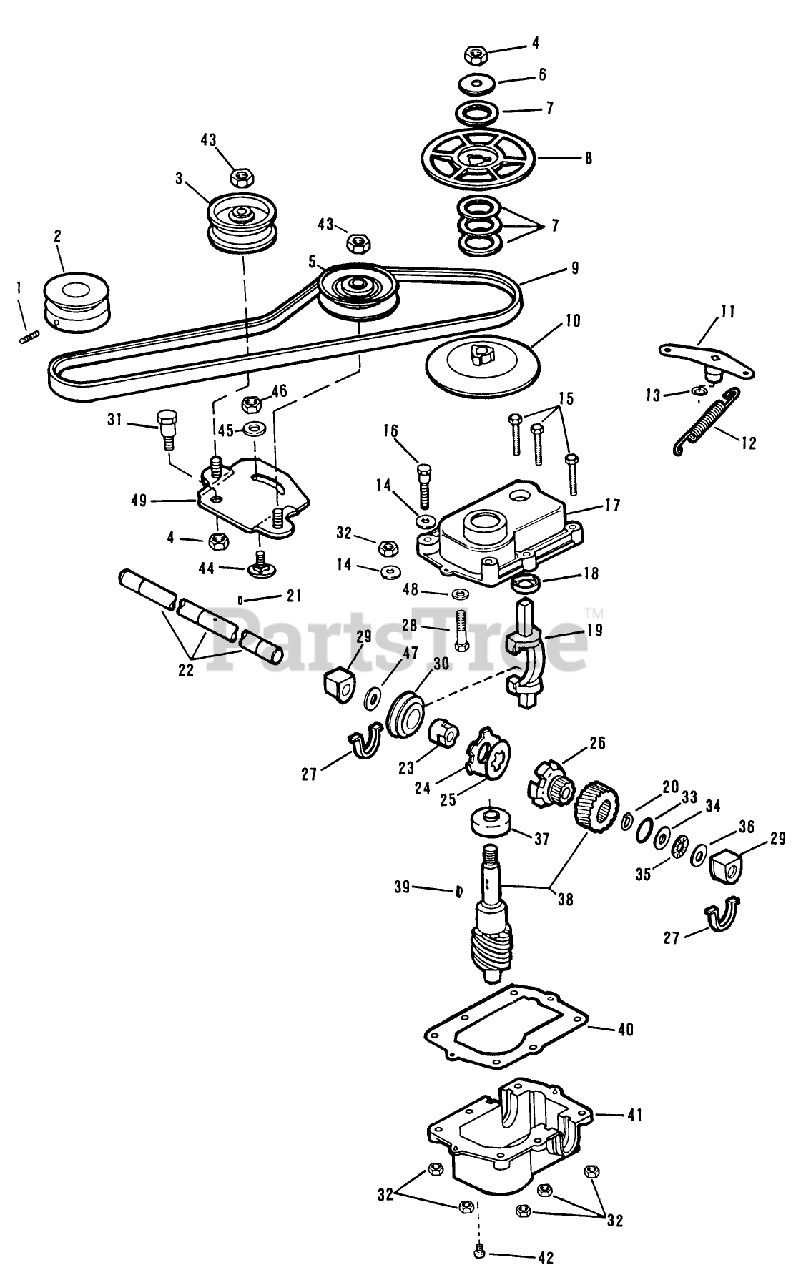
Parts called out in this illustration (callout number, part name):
1	SET SCREW F
2	PULLEY ENG F
3	PULLEY NEWHAM IND *B
4	LOCKNUT
5	IDLER NEW HAM IND
6	WASHER
8	PULLEY UPPER PL
9	V-BELT
10	PULLEY LOWER PL
12	SPRING
13	O-RING
18	GUIDE ELCO
19	FORK SHIFT
20	RET RING
21	PIN DRIVE LOCK
24	ORD 684683,
25	ORD KIT 684683
26	DRIVER BROCKWAY
29	BEARING & SEAL AY (12)
32	LOCKNUT E
34	WASHER-THRUST
36	THRUST WASHER
37	BEARING-BALL
39	KEY GALGER
40	GASKET HOOSIER
43	NUT-JAM, LOCKING
45	WASHER M
46	NUT-LOCK F
47	WASHER
